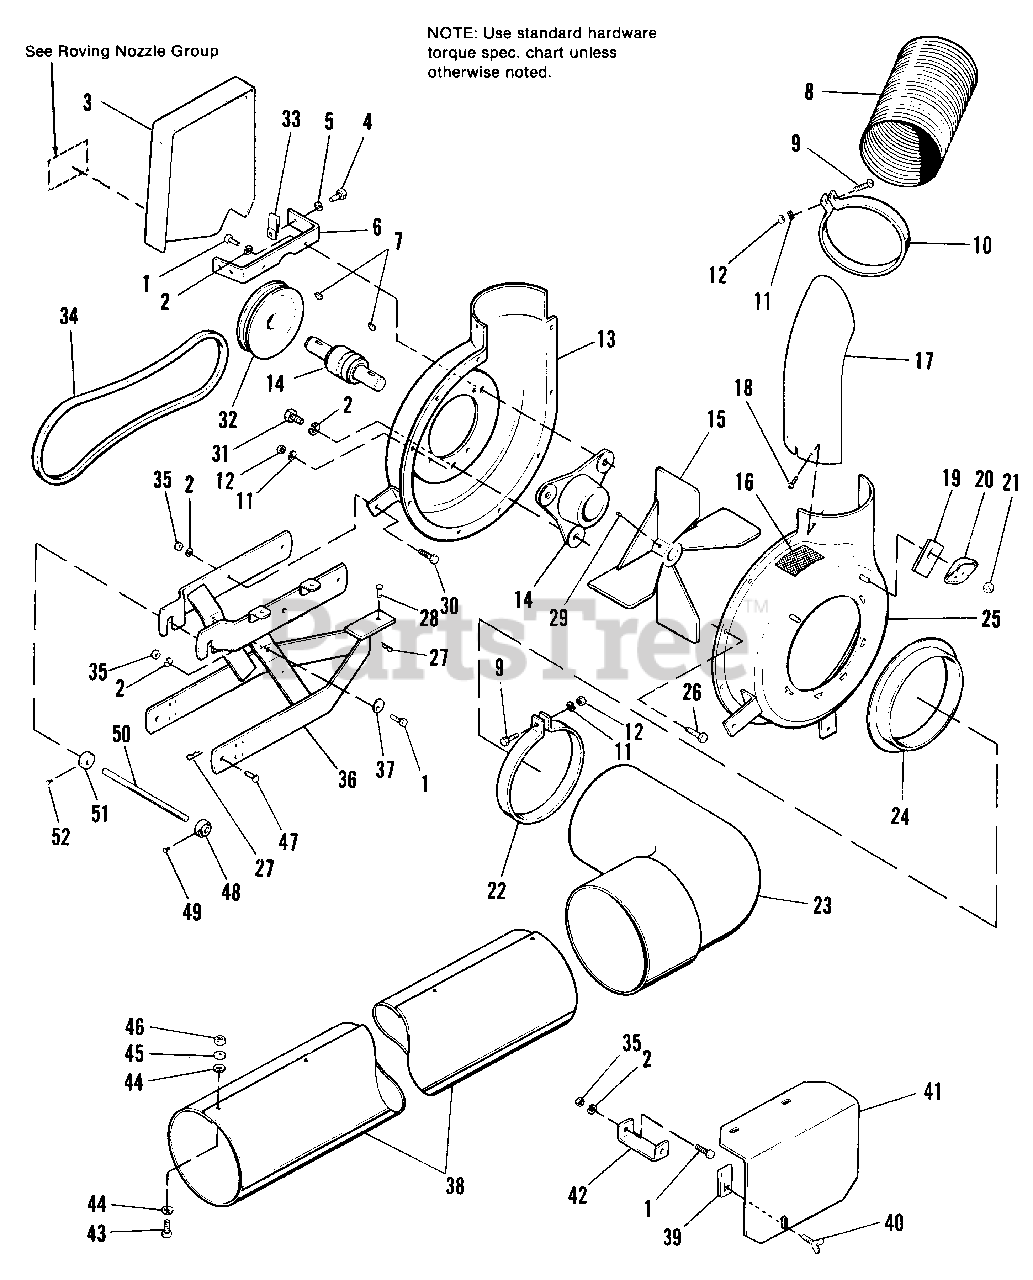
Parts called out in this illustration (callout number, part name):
1	CAPSCREW, Hex Hd., 3/8-16 x 1
2	LOCKWASHER, 3/8
3	GUARD, Belt
4	CAPSCREW, Hex Hd., 5/16-18 x 5/8
5	LOCKWASHER, 5/16
6	BRACKET, Belt Guard
7	KEY, Hi-Pro
8	HOSE, Exhaust
9	SCREW, Rd. Hd., 1/4-20 x 3
10	CLAMP, Hose
11	LOCKWASHER, 1/4
12	NUT, Hex, Full, 1/4-20
13	HOUSING HALF ASSY., Blower
14	BEARING ASSY., Flange & Shaft
16	DECAL, Caution
17	DEFLECTOR
18	SCREW, Round Hd., Thread Forming, #10 x 3/8
20	NUT, Wing
21	LOCKNUT, Hex, Jam, 5/16-18
22	CLAMP, Hose
23	ELBOW ASSY. (Incl. Ref. No. 24)
24	FLANGE, Hose
25	HOUSING ASSY.
26	CAPSCREW, Hex Hd., 1/4-20 x 1/2
27	PIN, Quick
28	PIN
29	SETSCREW, 5/16-18 x 1/2
30	CAPSCREW, Hex Hd., 3/8-16 x 1-1/4
31	CAPSCREW, Hex Hd., 3/8-16 x 3/4
33	NUT, Retainer, 5/16-18
35	NUT, Hex, Full, 3/8-16
36	SUPPORT ASSY., Blower Housing
37	WASHER, Eccentric
38	TUBE, Intake
39	NUT, Speed, 1/4-20
40	SCREW, Wing, 1/4-20 x 5/8
43	SCREW, Truss Hd., #10-32 x 1/2
44	WASHER, Plain, 3/16
45	LOCKWASHER, Int., #10
46	NUT, Hex, Mach., #10-32
48	COLLAR, Set
49	SETSCREW, 5/16-18 x 5/8
50	SHAFT, Lift
51	COLLAR, Set
52	SETSCREW, Sq. Hd., Cup Pt., 5/16-18 x 1/2
